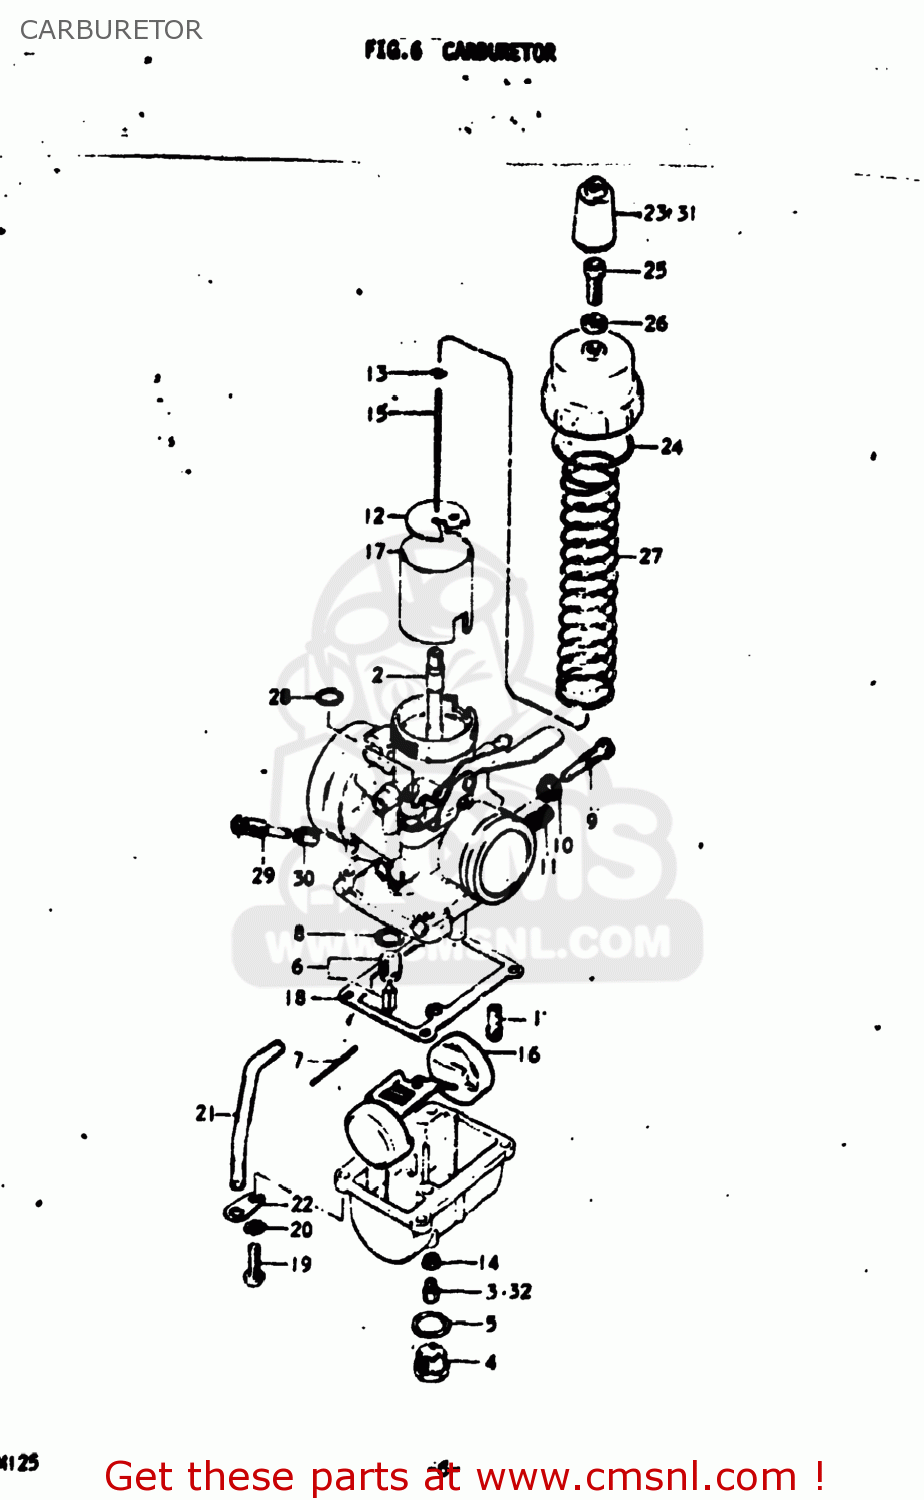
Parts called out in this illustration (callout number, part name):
0	CARBURETOR ASSEMBLY
1	JET
2	JET,NEEDLE
3	JET
4	PLUG
5	GASKET,DRAIN PLUG (MCA)
6	VALVE ASSEMBLY,NEEDLE
7	PIN,FLOAT
8	GASKET,VALVE SEAT (NAS)
9	ADJUSTER
10	NUT, STOP SCREW
11	SPRING,THROTTLE SCREW
12	PLATE,THROTTLE VALVE
13	CLIP
14	RING
15	NEEDLE JET
16	FLOAT
17	VALVE,THROTTLE,RIGHT
18	GASKET,FLOAT CHAMBER
19	SCREW
20	LOCK WASHER
21	HOSE
22	PLATE
23	CAP
24	O-RING
25	ADJUSTER,CABLE
26	NUT,CABLE ADJUSTER LOCK
27	SPRING
28	O RING
29	SCREW,PILOT AIR
30	SPRING
31	CAP
32	JET
